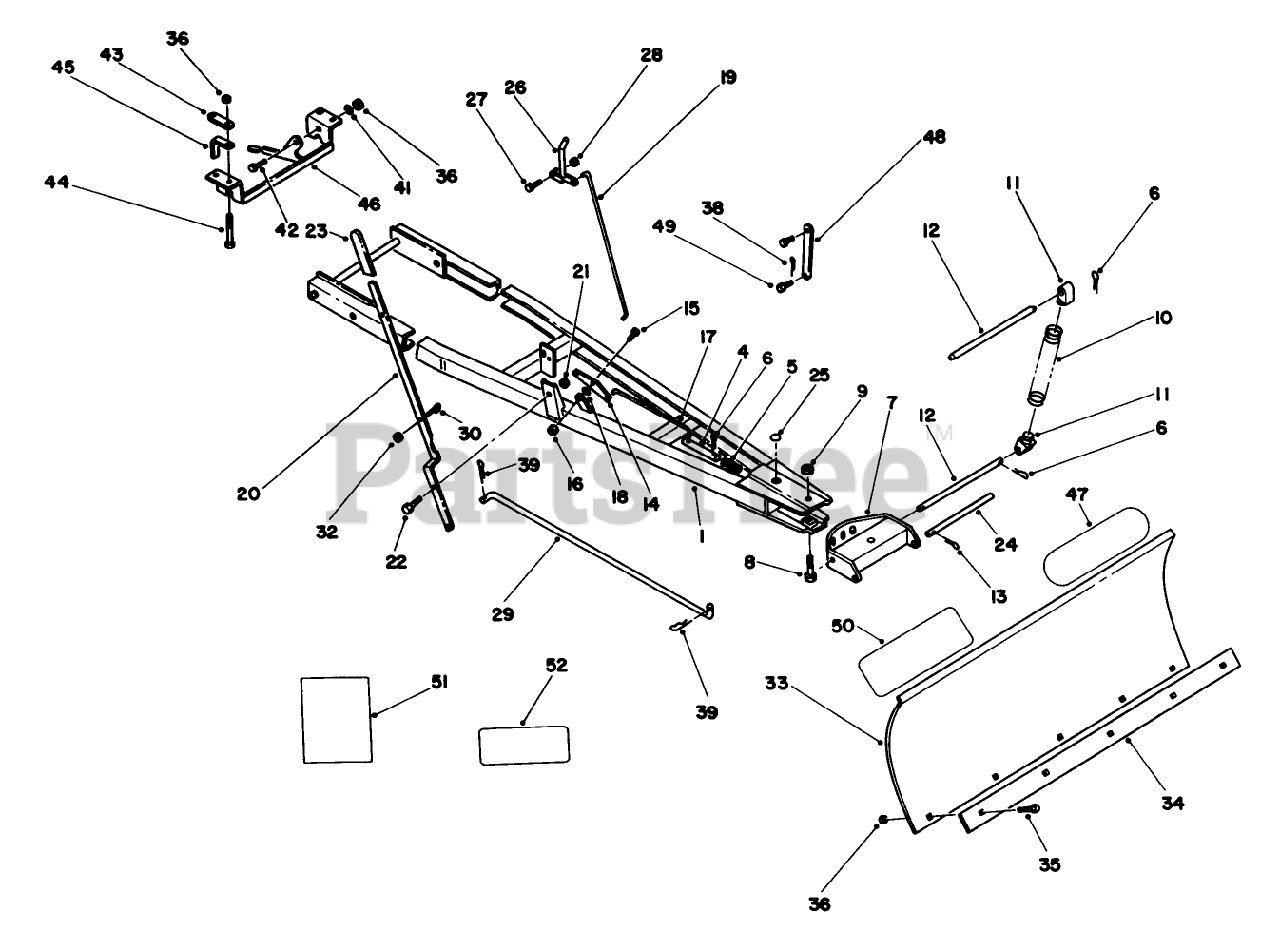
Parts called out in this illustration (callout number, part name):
1	Frame Assembly (Incl. Ref. #4-6)
4	Index Pin
5	SPRING-COMPRESSION
7	Decal
8	Bolt
9	Nut
10	Spring
11	Lug
12	ROD-PIVOT, BLADE
13	Hairpin
14	Index Plate
15	SCREW-HH
16	NUT
17	Head-Cylinder
18	WASHER-FLAT
19	UPPER INDEX ROD
20	Index Lever
21	Jam Nut
22	Bolt
23	GRIP
24	ROD-LOWER
25	PLUG
26	INDEX LEVER
27	SCREW-HH
28	Nut
30	EYEBOLT
32	Nut
33	Blade
34	Blade Edge Plate
35	Bolt-Carriage
36	NUT
38	Hairpin Cotter
39	Hairpin
40	PLATE-LATCHING
41	Washer
42	BOLT
43	BRACKET-REAR LINK MOUNTING
44	Bolt-Carriage
45	SPACER-BRACKET
46	Bracket
47	DECAL - REAR FRAME
48	LINK-LIFT
49	Pin
50	DECAL-DANGER
51	OPERATOR'S-MANUAL
52	DECAL-OVERLAY
